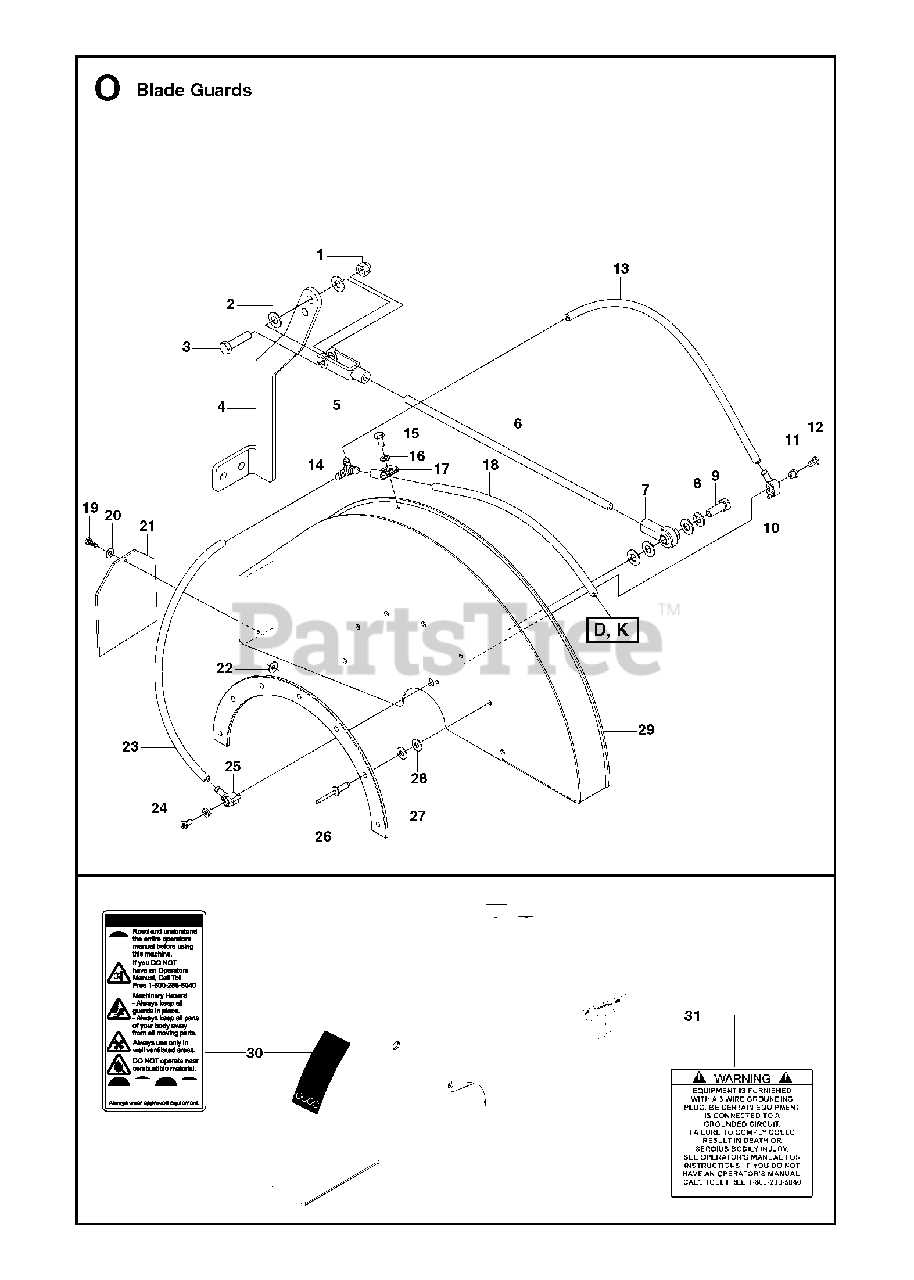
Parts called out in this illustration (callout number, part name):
1	NUT
2	WASHER
8	WASHER
12	SCREW ITXSCM
15	HCS ¼-20 X ½ GR 5 ZD
16	WASHER
18	HOSE
28	WASHER 1/4 SAE
